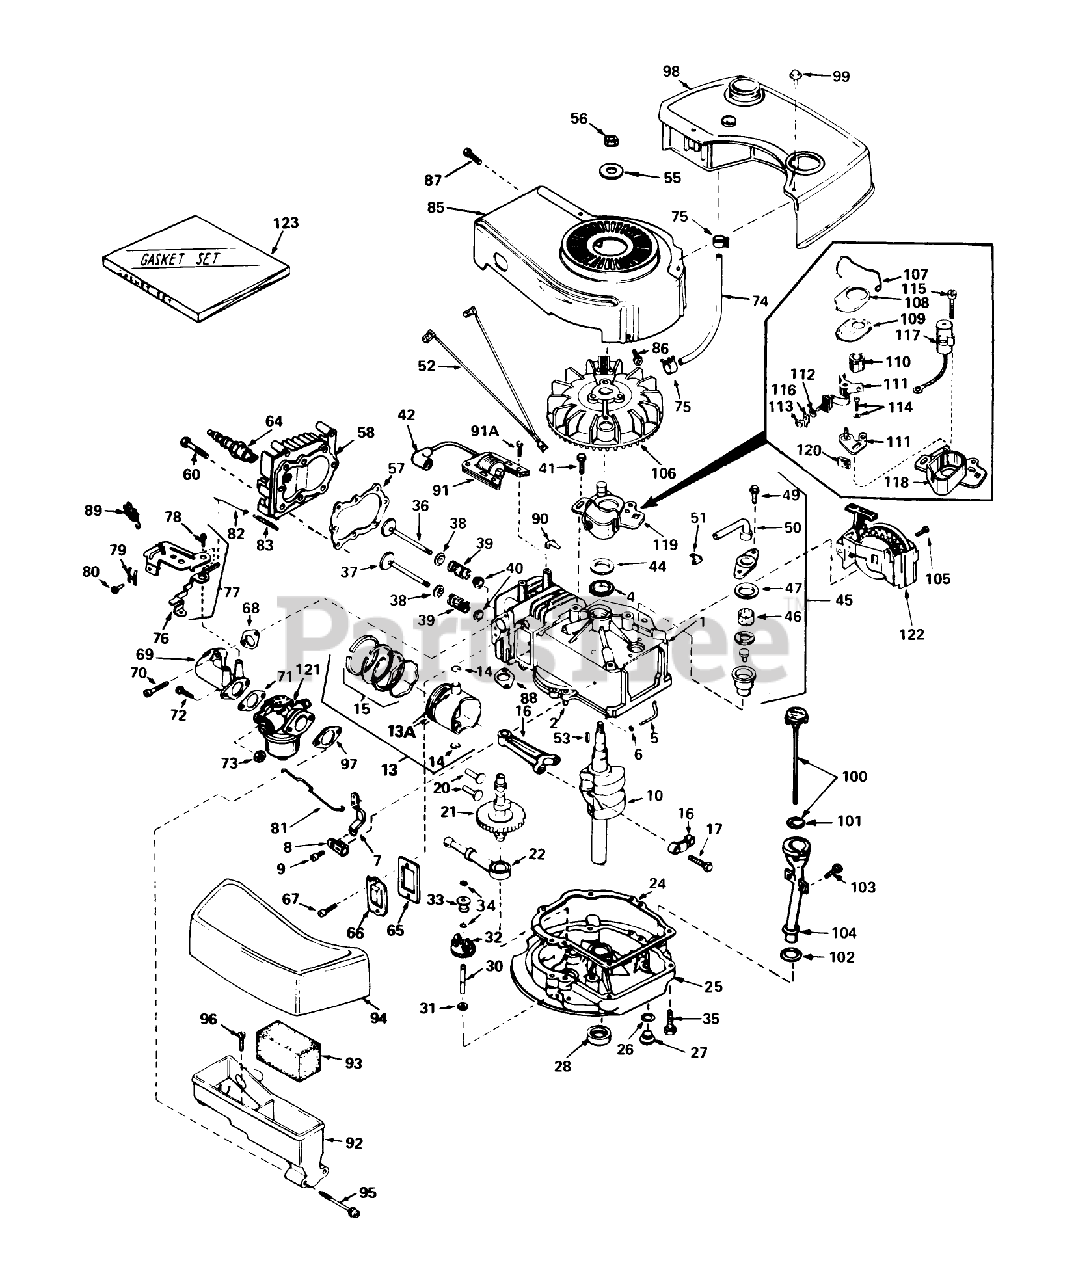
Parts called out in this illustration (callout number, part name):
1	Cyiinder Assy. (Incl. Ref. #2, 4 105)
2	Pin-Dowel
4	Seal-Oil
5	Rod, Governor (Incl. No. 36)
6	Washer-Flat
7	Governor Lever
8	Clamp-Lever, Governor
9	Screw
10	Crankshaft
13	Piston, Pin Ring Assy. (Std.)(Incl. Ref. #13A, 14 15)
13	Piston,Pin Ring Assy. (.010 over-size)(Incl. Ref. #13A, 14 15)
13	Piston, Pin Ring Assy. (Incl. Nos. 13A, 14 15)(.020 oversize)
13A	Piston Pin Assy. (Incl . Ref. . #14) (Std.)
13A	Piston Pin Assy. (Incl. Ref. #14) (.010 Oversize)
13A	Piston Pin Assy. (.020 oversize) (Incl. Ref. #14)
14	Ring-Retaining, Piston Pin
15	Ring Set Piston (Std.)
15	Ring Set Piston (.010 Oversize)
15	Ring Set Piston (.020 Oversize)
16	Rod Assy., Connecting (Incl. Ref. #17)
17	Bolt-Rod, Connecting
20	Lifter-Valve
21	Camshaft(Mech.Comp. Release)
22	Oil Pump ASM
24	Gasket, Mounting
25	Flange Assy., Mounting (Incl. Ref. #26thru 30)
26	Gasket-Oil Drain
27	Plug Oil Drain
28	Seal Oil
30	Shaft-Governor
31	Washer-Flat
32	Governor Gear ASM
33	Spool-Governor
34	Ring-Retaining
35	Screw (1/4-20 x 1-1/4)
36	Valve, Intake (Incl. Ref. #38, 39 40) (Std.)
36	Valve, Exhaust (1/32" Oversize) (Incl. Nos. 8, 9 10)
37	Valve, Exhaust (Standard) (Incl. Nos. 8, 9 10)
37	Valve, Exhaust (1/32" Oversize) (Incl. Nos. 8, 9 10)
38	Cap-Upper Valve Spring
39	Spring-Valve
40	Cap-Valve, Spring
41	Screw
42	Cover-Spark Plug
44	Gasket Stator
45	Breather Assy. (Incl. Ref. #46, 47, 49, 50 51 )
46	Element-Breather
47	Gasket-Breather
49	Screw (10-24 x 9/16)
50	Tube, Breaker
51	Clip, Breather
52	Wire Ground
53	682488 LB GRASS HI-
55	Washer-Belleville
56	Nut-Flywheel
57	63573 GIL 42 SNWTHW
58	Head-Cylinder
60	Screw (5/16-18x1-1/2)
64	Plug, Spark (J17LM or equiv.)
64	Plug, Spark (Champion RCJ-8)
65	Gasket-Breather
66	Cover-Valve
67	Screw
68	Gasket, Intake
69	Pipe, Intake
70	Screw (1/4-20 x 1)
71	Gasket-Carburetor
73	Nut and Lock Washer (1/4-28)
74	Line-Fuel
75	Clamp-Line, Fuel
76	Lever Control
77	Control Assy., Speed (Incl. Nos, 76, 78 89)
78	Screw, Hex Washer Hd Shoulder Self-Tap
79	Conduit
80	Screw (10-32 x 3/8)
81	Link-Throttle
82	Link Governor Spring
83	Spring Governor
85	Housing Blower
86	Screw
87	Screw (10-24 x 9/16)
88	Gasket Exhaust
89	Terminal
90	Clip-Wire
91	Lamination Coil Assy. (Incl. No. 42)
91A	Screw
92	Body Air Cleaner
93	Filer, Air
94	Cove, Air Cleaner
95	Screw Fil Hd.
96	Screw, Hex Hd.
97	Gasket-Air Cleaner
98	Tank, Fuel
99	Screw (10-32 x 35/64)
100	Dipstick, Oil (Incl. Ref. #101)(Twist Lock)
101	O-Ring
102	Gasket
103	Screw (10-32 x 1/2)
104	Tube-Oil Fill
105	Screw (1/4-20 x 1/2)
106	FIywheel
107	Spring Breaker Box
108	Cover-Dust
109	Gasket-Dust Cover
110	Cam-Breaker
111	Breaker Assy.
112	Washer
113	DECAL
114	Breaker Screw
115	Condenser Screw
116	Terminal, Ground
117	Condenser
118	Stator Plate
119	Stator Plate Assy. (incl. Nos. 107, 111 thru 118 120)
120	Felt,Cam Wiper
121	Carburetor (Incl. Ref. #71 )
122	Starter, Side Mount
123	53024/VAR.16HP O/P
